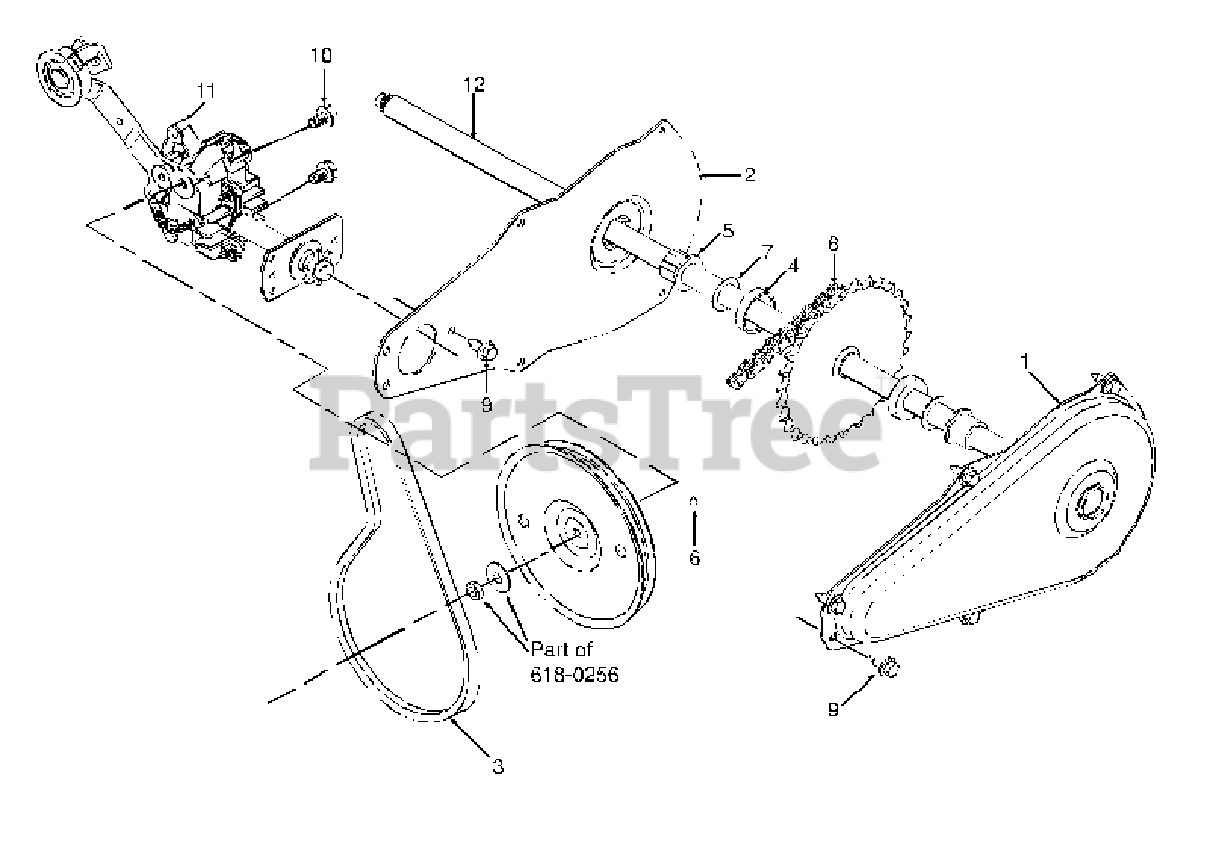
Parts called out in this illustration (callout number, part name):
3	V-BELT 3/8 x 24.68
4	SPACER .630 x 1.25 x .290
5	HEX FLANGE BEARING .631 x .720
6	BEALENE GREASE
7	FLAT WASHER 5/8 x 1.00 x .030
8	CHAIN #41 x .500
9	HEX WASH HD. AB-TAP SCREW 1/4-20 x .625"
10	HEX WASH HD. TYPE B SCREW 5/16-18 x .50"
11	TRANSMISSION ASS'Y.
12	SHAFT: AXLE ASSEMBLY
